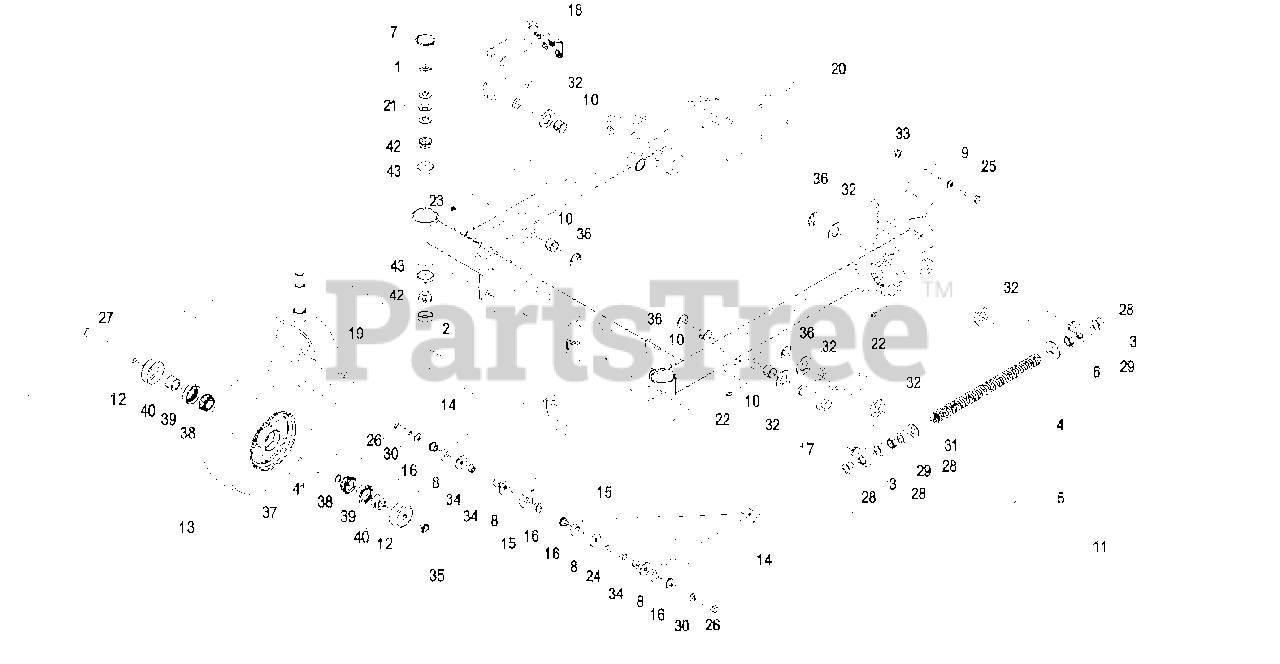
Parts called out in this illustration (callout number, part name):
1	NUT-LOCK, NI
2	SEAL-GREASE
3	SWIVEL-DECK MOUNT, REAR
4	SPRING-COMPRESSION
5	ROD-LIFT, DECK
7	CAP-GREASE
9	WASHER-BELLEVILLE
10	BUSHING,SPRING
11	FRONT SPRING ASM
12	GUARD-SEAL
13	WHEEL AND TIRE ASM
14	FLAT,STRUT
15	FLAT,STRUT ANGLED
16	SPACER-STRUT
17	WLD,SHAFT LH
19	FORK-CASTER
20	Asm, Front Frame (52")
21	WASHER-BELLVILLE
22	FITTING-GREASE
24	SCREW-HH
25	SCREW-HH
26	SCREW-HH
27	SCREW-HH
28	NUT-HEX
29	NUT-JAM
30	WASHER-FLAT
31	WASHER-FLAT
32	WASHER-FLAT
33	NUT-HHF, WHIZ
34	NUT-LOCK, NI
35	NUT-HEX
36	RING-RETAINING, EXT
38	BEARING-CONE, TAPERED ROLLER
39	SEAL-CASTER
40	SPACER-NUT
42	Cone-Bearing Tapered Roller
43	CUP-BEARING
